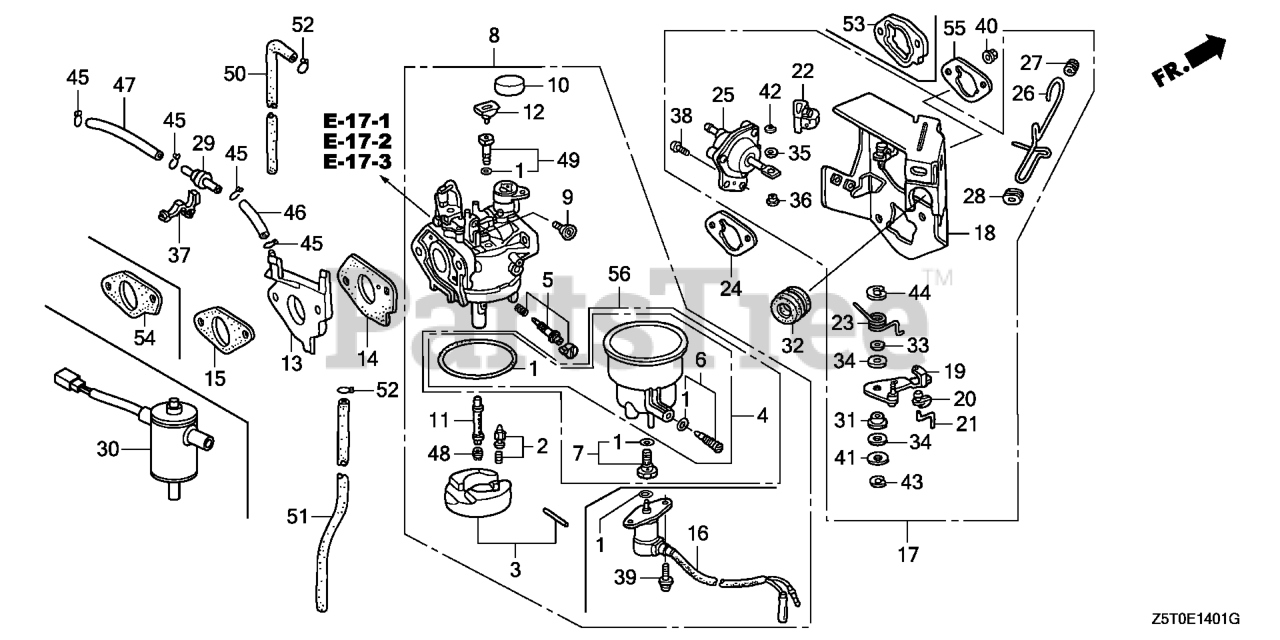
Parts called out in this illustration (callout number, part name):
1	GASKET SET
2	VALVE SET, FLOAT
3	FLOAT SET (CARBURETOR NO.)
5	SCREW SET (CARBURETOR NO.)
6	SCREW SET, DRAIN (ADVENTURE GREEN) (CARBURETOR NO.)
8	CARBURETOR ASSY. (BEC1A A)
9	SCREW, THROTTLE STOP
10	CAP, CHOKE LEVER DUST
11	NOZZLE, MAIN
12	COLLAR, SET
13	INSULATOR, CARBURETOR
14	GASKET, CARBURETOR
17	STAY ASSY., MANUAL CHOKE
18	STAY, SOLENOID
19	LEVER, CHOKE
20	JOINT, ROD
21	ROD, CHOKE
22	STOPPER, CHOKE ROD
23	SPRING, MANUAL CHOKE
24	GASKET, AIR CLEANER
25	DIAPHRAGM ASSY.
26	ROD, CHOKE CONTROL
27	GROMMET, CHOKE ROD
28	GUIDE, CHOKE ROD
29	VALVE, DASHPOT CHECK
31	BUSH, ARM PIVOT
32	GROMMET, FENDER
33	WASHER, CHOKE LEVER
34	SEAL, CHOKE LEVER
35	WASHER, THRUST (2.7X8)
36	COLLAR, LEVER
37	CLIP, WIRE HARNESS
38	SCREW, PAN (5X12)
40	NUT, FLANGE (6MM)
41	WASHER, PLAIN (5MM)
42	E-RING (2MM)
43	E-RING (4MM)
44	E-RING (7MM)
45	CLIP, TUBE (B7)
46	BULK HOSE, VACUUM (3.5X8000) (3.5X130)
47	BULK HOSE, VACUUM (3.5X8000) (3.5X130)
48	JET, MAIN (#110) (CARBURETOR NO.)
48	JET, MAIN (#112)
48	JET, MAIN (#115)
49	JET SET, PILOT (#45) (CARBURETOR NO.)
53	SPACER, CARBURETOR
54	GASKET, CARBURETOR INSULATOR
56	BOLT KIT, FUEL CHAMBER
